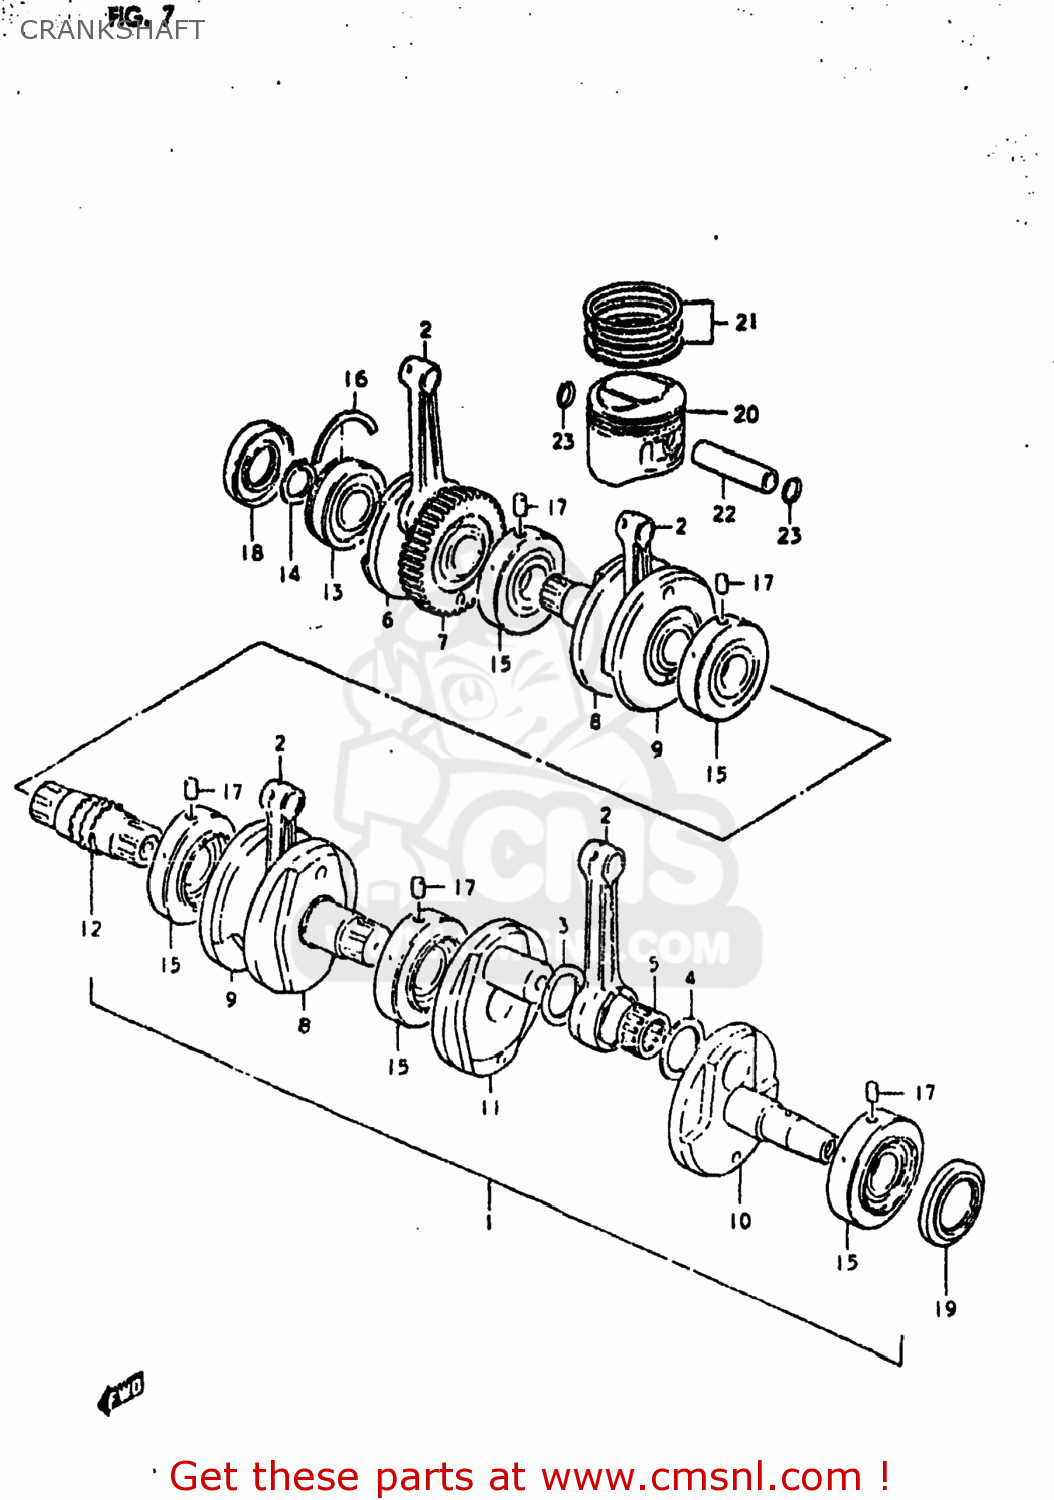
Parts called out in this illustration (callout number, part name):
1	CRANKSHAFT ASSEMBLY
2	ROD,CONNECTING
3	WASHER (28X48X2)
4	WASHER(28X48X1)
5	ROLLER BEARING (28X38X16.8)
6	CRANKSHAFT
7	WEB,CRANK
8	CRANKSHAFT
9	WEB,CRANK,MIDDLE
10	CRANKSHAFT,LEFT
11	WEB,CRANK,LEFT
12	SHAFT,TIMING CHAIN DRIVE
13	BEARING(30X72X19)
14	CIRCLIP,30MM
15	BEARING
16	C RING
17	PIN
18	SEAL,OIL(30X72X11)
19	OIL SEAL
20	PISTON
21	RING SET,PISTON
22	PIN,PISTON 16MM
23	CIRCLIP
